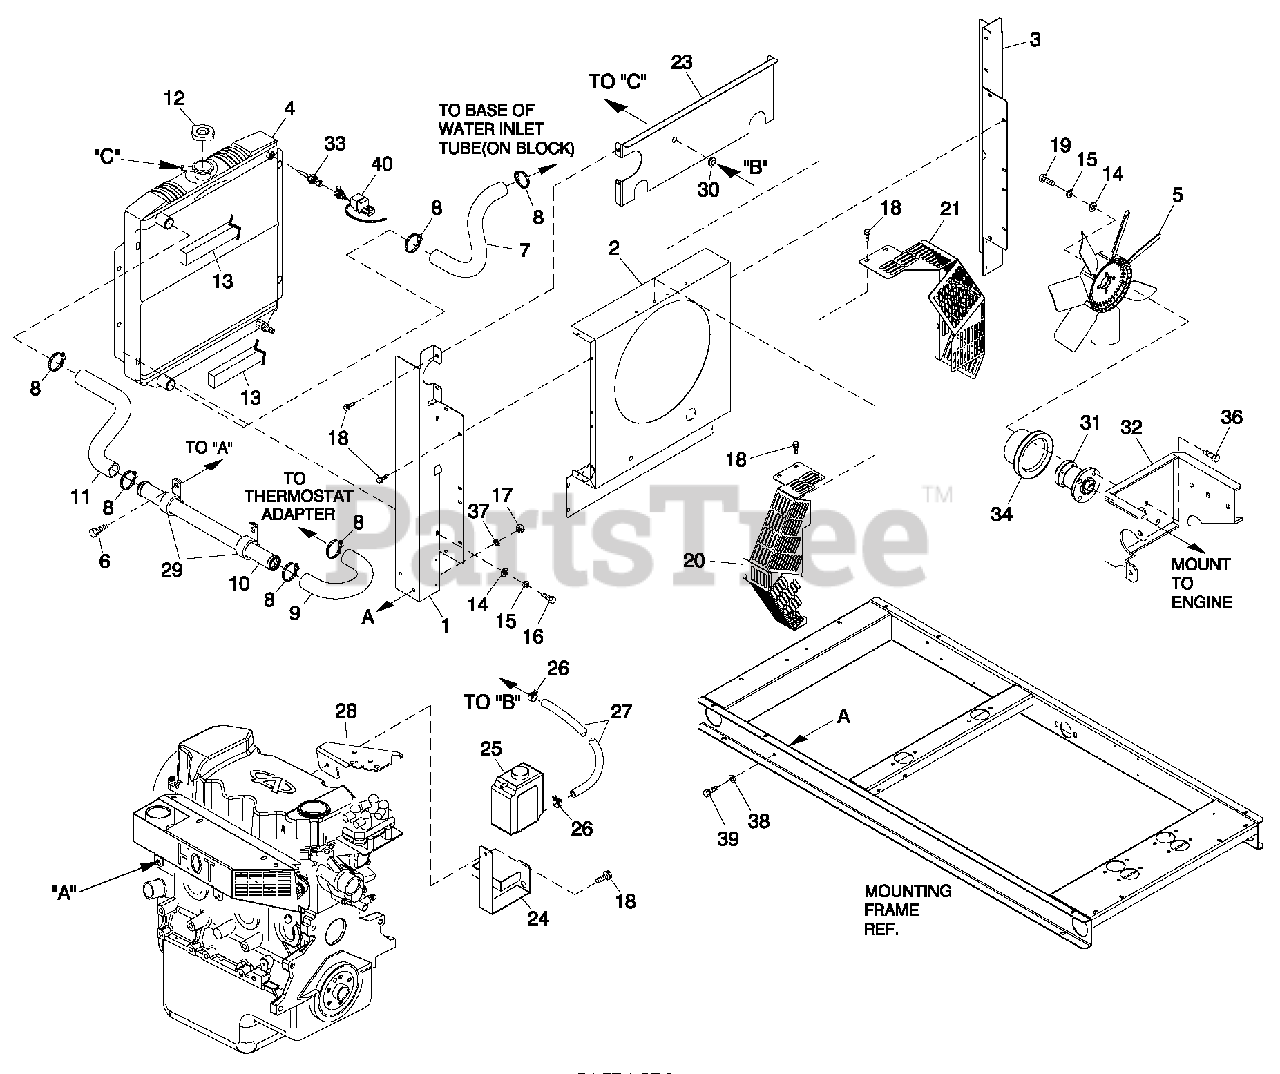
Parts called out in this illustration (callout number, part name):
1	RADIATOR SUPPORT LH SIDE 1.6L
2	VENTURI 1.6L
3	RADIATOR SUPPORT RH SIDE 1.6L
4	RADIATOR 1.6L CHY
5	FAN COOL 450MM DIA 7 BLADE
6	SCREW HWHTF M6-1.0X16
7	HOSE LOWER RADIATOR 1.6L
8	CLAMP HOSE #24 B1.06-2.00
9	HOSE REAR COOLANT 1.6L
10	TUBE ENGINE COOLANT 1.6L
11	HOSE UPPER RADIATOR 1.6L
12	CAP RADIATOR
13	TAPE FOAM 1 X 1 (24" LG)
14	WASHER FLAT 1/4-M6 ZINC
15	WASHER LOCK M6-1/4
16	SCREW HHFCM6-1.0X 20 G8.8
17	NUT HEX M8-1.25 G8 CLEAR ZINC
18	SCREW THF M6-1 X 12 N WA Z/JS
19	SCREW HHC M6-1.0X20G8.8
20	GUARD FAN LH C1
21	GUARD FAN RH C1
23	RADIATOR BLOCK-OFF
24	BRACKET COOLANT TANK
25	TANK COOLANT RECOVERY
26	CLAMP HOSE BAND 1/4
27	HOSE 9/32 ID (43" LG)
28	BRACKET STEPPER MOTOR COOLANT
29	CLAMP VINYL 1.31 X.281Z
30	GROMMET 5/8"X 1 1/8"X5/16"
31	ASSY FAN BEARING SUPPORT
32	BRACKET FAN ALT ADAPTER 1.6L
33	PROBE COOLANT LEVEL 3/8NPTF
34	PULLEY - FAN 95 DIA
36	SCREW HHC M8-1.25X 16 G8.8
37	WASHER SHAKEPROOF EXT 5/16 STL
38	WASHER LOCK M8-5/16
39	SCREW HHC M8-1.25X20 G8.8
40	ASSY PCB LCL SENSOR (USE WITH I/N 33, P/N 0H1827 ONLY)
